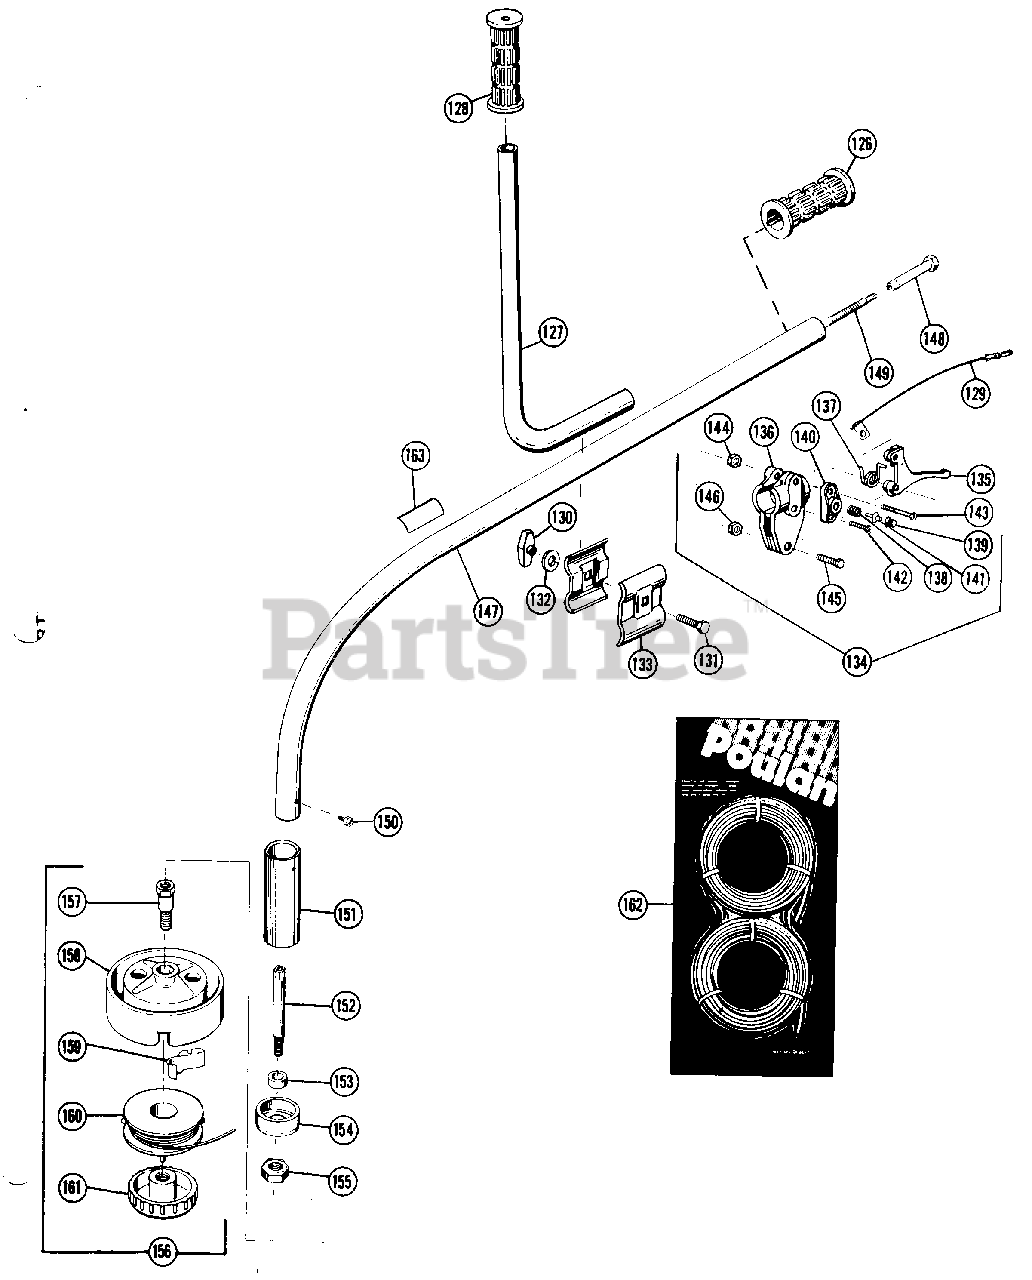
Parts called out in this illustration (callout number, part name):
126	Grip-drive shaft
127	Handle bar w/grip
128	Grip-handle bar
129	Lead wire switch
130	Knob-handle bar clamp
131	Bolt-clamp
132	Washer-clamp
133	Clamp-handle
134	Throttle control - assembly (inc.135-146)
137	Spring-trigger
138	Spring-switch
142	Screw-cap
143	Screw-housing clamp
144	Nut-housing clamp
145	Screw-trigger
146	Nut-trigger
147	Drive shaft assy.
148	Upper coupling
149	Flexible drive shaft
150	Screw-bearing housing
151	Bearing housing assy.
152	Arbor shaft
154	Dust cap
156	Cutting head assembly (inc.157-161)
157	Bolt drive adaptor
159	Line saver
160	Cutting head spool w/line
161	Ball lock
162	Cutting line skin pack
163	Label/decal
